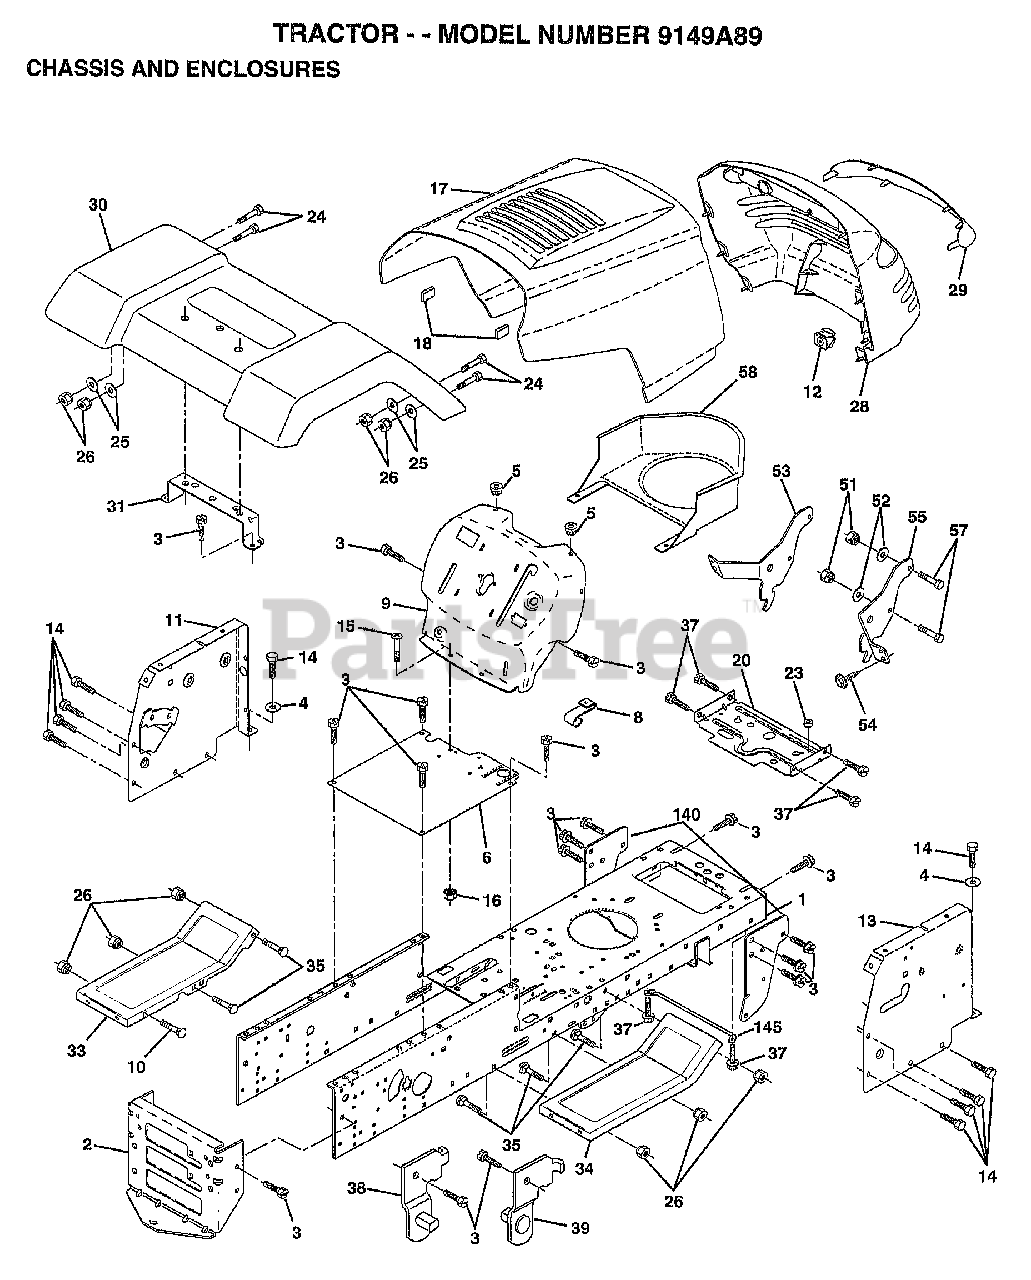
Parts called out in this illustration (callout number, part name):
3	SCREW
4	WASHER
5	BUMPER-HOOD/DASH
6	SADDLE
8	CLIP.RETAINER
9	DASH SILKSCREEN
11	"PANEL-DASH,LH"
12	CLIP.TINNERMAN
14	SCREW LT
15	SCREW
17	HOOD.STEEL.ASSY
20	"PLATE-MTG,BATT/FU"
24	BOLT
25	WASHER
26	NUT
28	GRILLE-MS428
29	LENS GRILLE
30	FENDER.LT.W/SHIFT
31	BRKT FENDER
33	FOOTREST.LH.LT/GT
34	FOOTREST.RH.LT/GT
35	BOLT
38	BRACKET ASM LH
39	BRACKET ASM RH
51	NUT
52	WASHER
53	BRACKET.GRILLE.LH
54	SCREW.HEX.WS.HD
55	BRACKET.GRILLE.RH
58	AIR DUCT
140	BRKT SUSPENSION
145	"ROD POVOT,CHASSIS"
